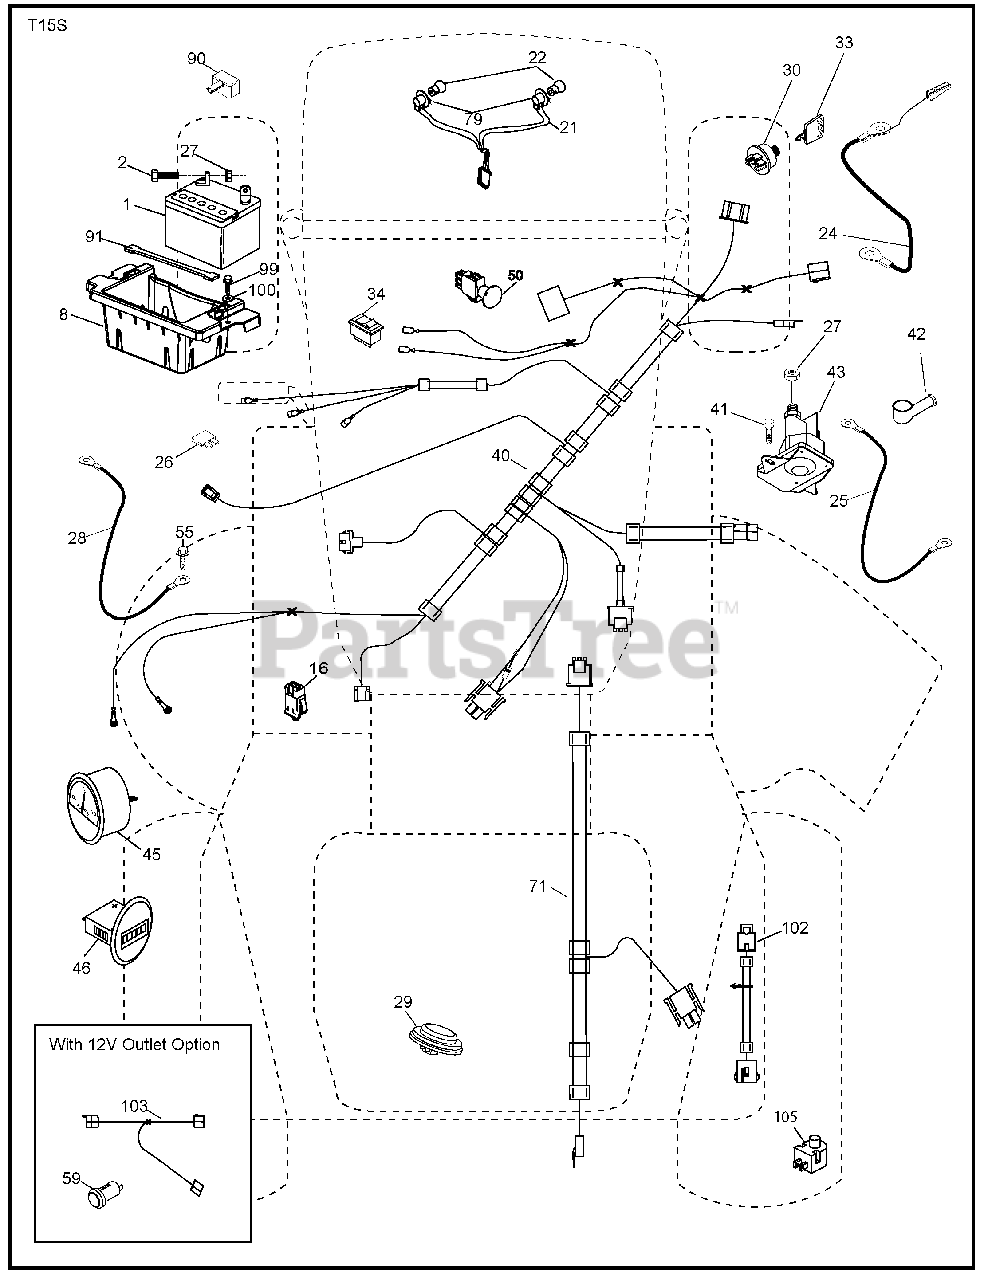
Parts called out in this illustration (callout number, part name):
1	Battery
2	Bolt Hex Head 1/4-20 x 3/4
8	Box Battery
16	Switch Interlock Push-In
21	Harness Socket Light w/4152J
22	Bulb Light
24	Cable Battery 8"
25	Cable Starter
27	Nut Keps Hex 1/4-20 unc
28	Cable, Ground
29	Switch, Seat
30	Switch, Ign
34	Switch Light / Reset
40	Harness Ign. Dash
41	Screw Thd Cut 1/4-20 x 1/2
42	Cover, Terminal
43	Solenoid
45	Ammeter Gauge Round Snap-In
46	Gauge Hrmtr
50	Switch PTO
55	Screw Thdrol 5/16-18 x 3/4 TYTT
59	Outlet 12-Volt
71	Harness Ign.
79	Socket Asm Bulb Twistlock
90	Cover Terminal
91	Strap Battery Mount Front
99	Screw Hexwsh Thdrol 1/4-20 x 3/4
100	Washer 9/32 x 7/8 x 16 Ga.
102	Harness Pigtail
103	Harness 12-Volt Pigtail
105	Switch Reverse TT Pedal Control
